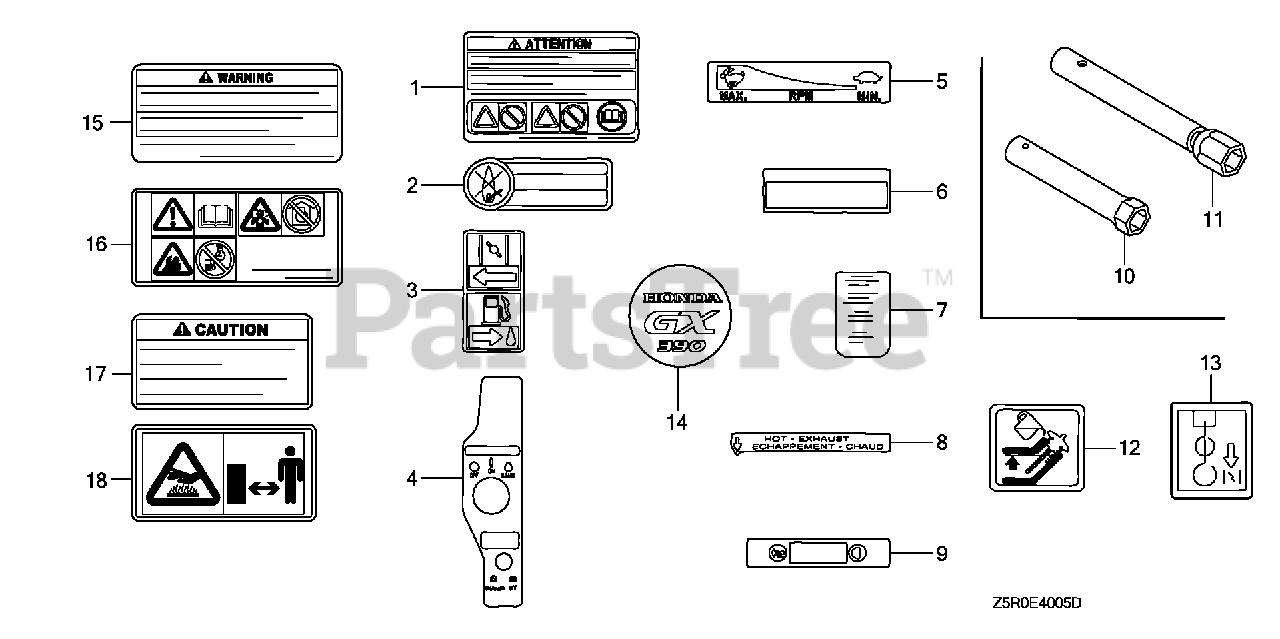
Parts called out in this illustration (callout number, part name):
15	MARK, OPERATOR CAUTION (FRENCH)(MADE IN JAPAN)
16	MARK, OPERATOR CAUTION (PICTOGRAPH)
17	MARK, EX. CAUTION (FRENCH)
18	MARK, EX. CAUTION (PICTOGRAPH)
